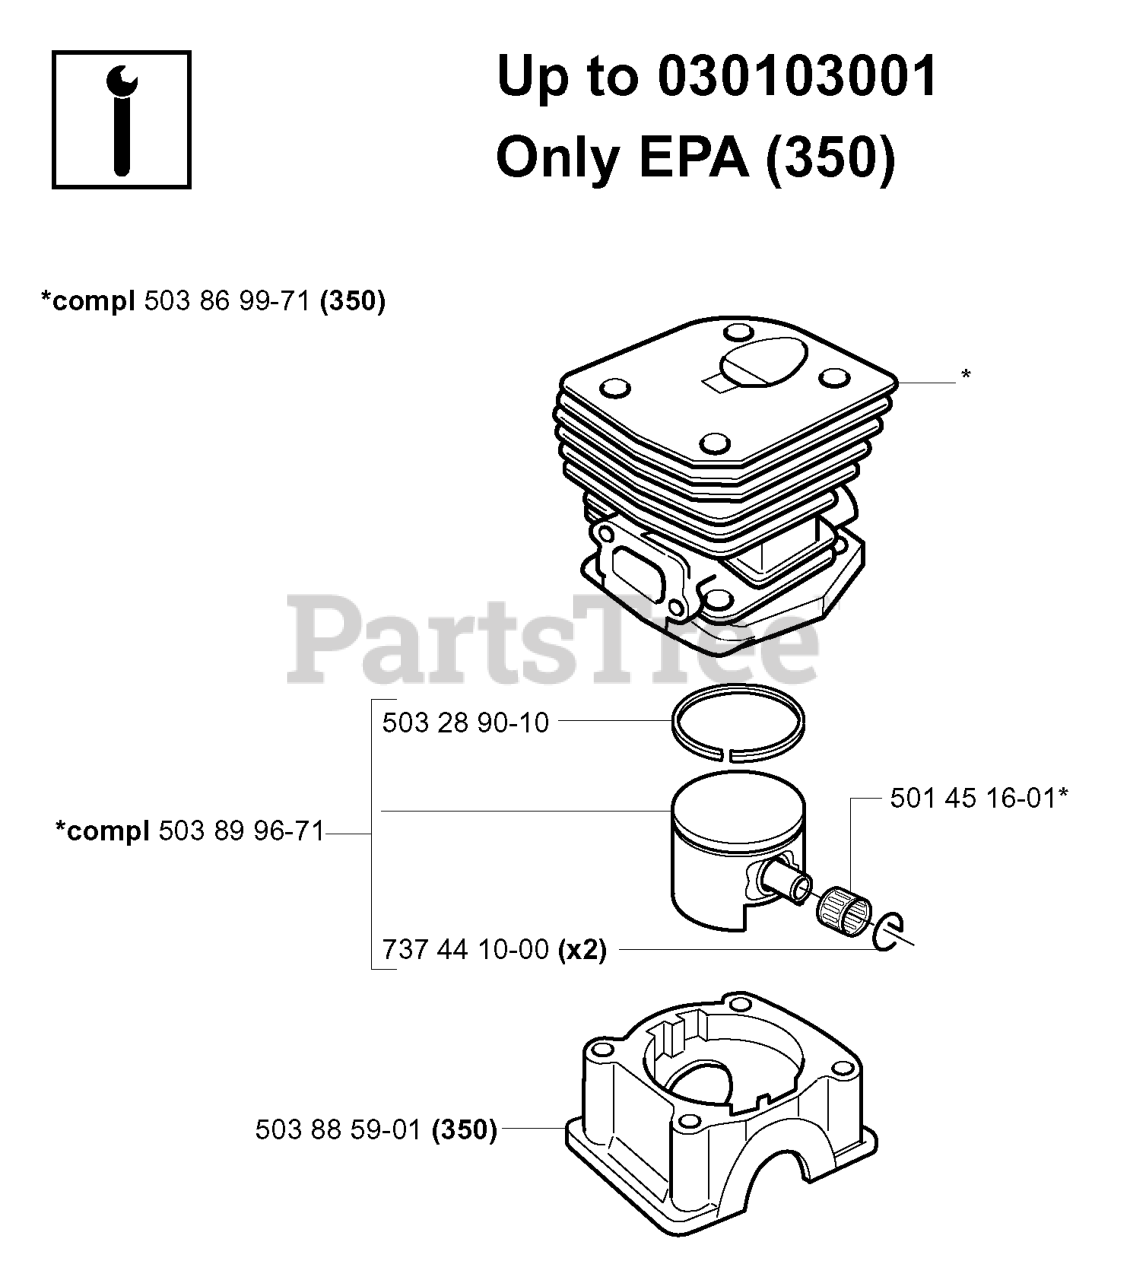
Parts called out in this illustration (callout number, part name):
2	DECAL PARK BRAKE
3	RP.DECAL.BADGE.170MM.TEXTLOGO
4	DECAL
5	DECAL V BELT SCHEMATIC
7	DECAL.INTERNATIONL.CUTFINGER
9	DECAL
10	LABEL
11	DECAL BTRY SYMBOLS
12	DECAL
15	DECAL
17	DECAL, DEFLECT WARNING
18	DECAL 80 DBA
